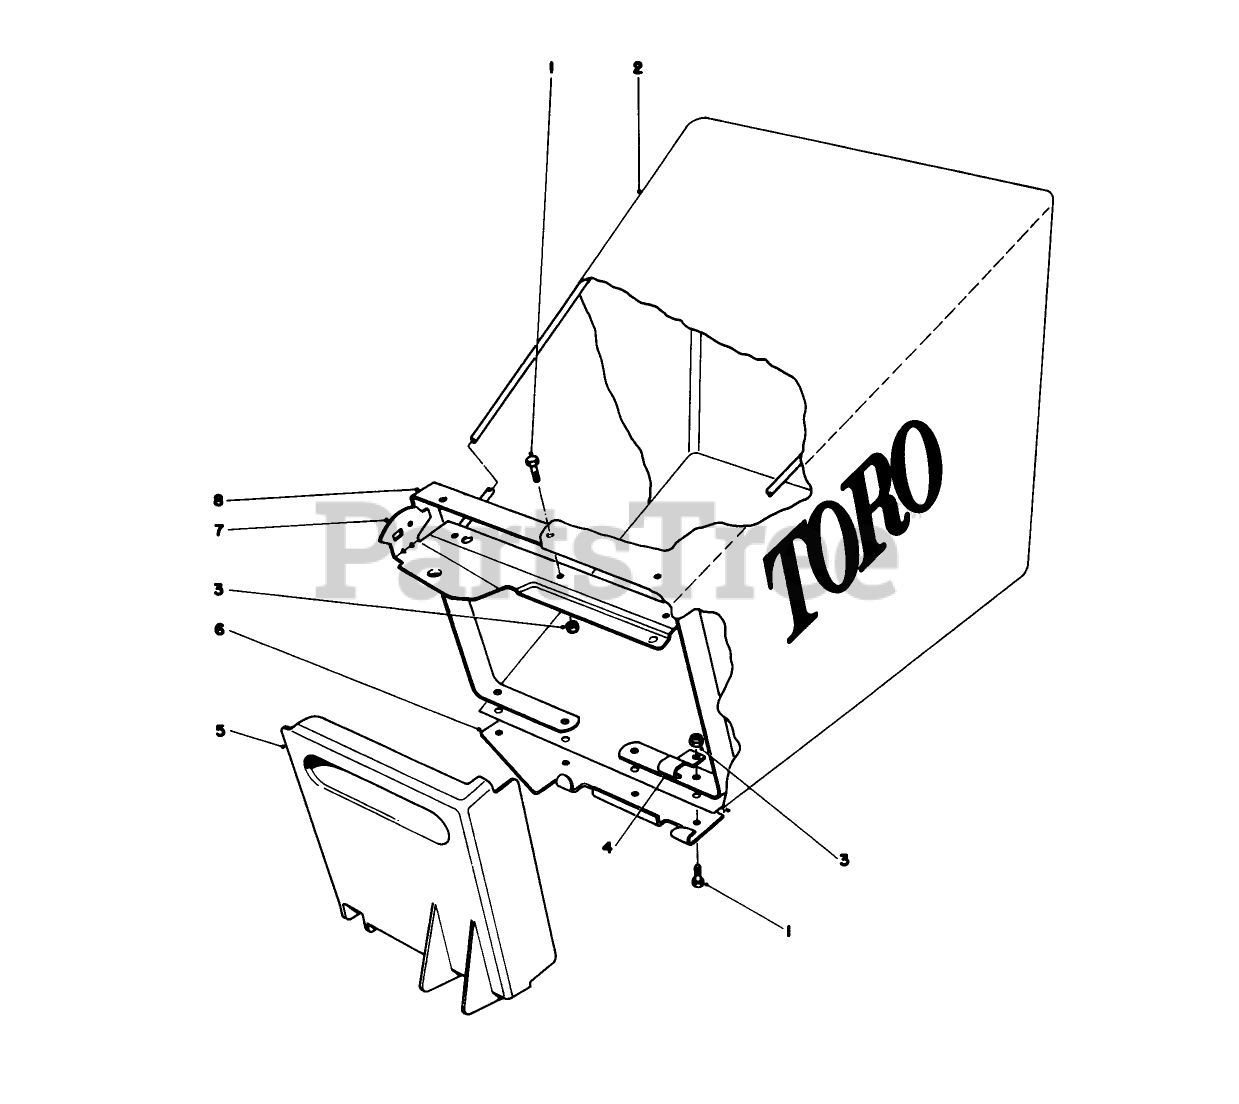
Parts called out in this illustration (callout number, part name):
1	SCREW-HWH
2	REPLACMNT BAG 44-0530
3	Locknut
4	SUPPORT BRACKET
5	BAG DOOR
6	DOOR BRACKET
7	BAG FRAME WA
8	LOWER BAG FRAME
